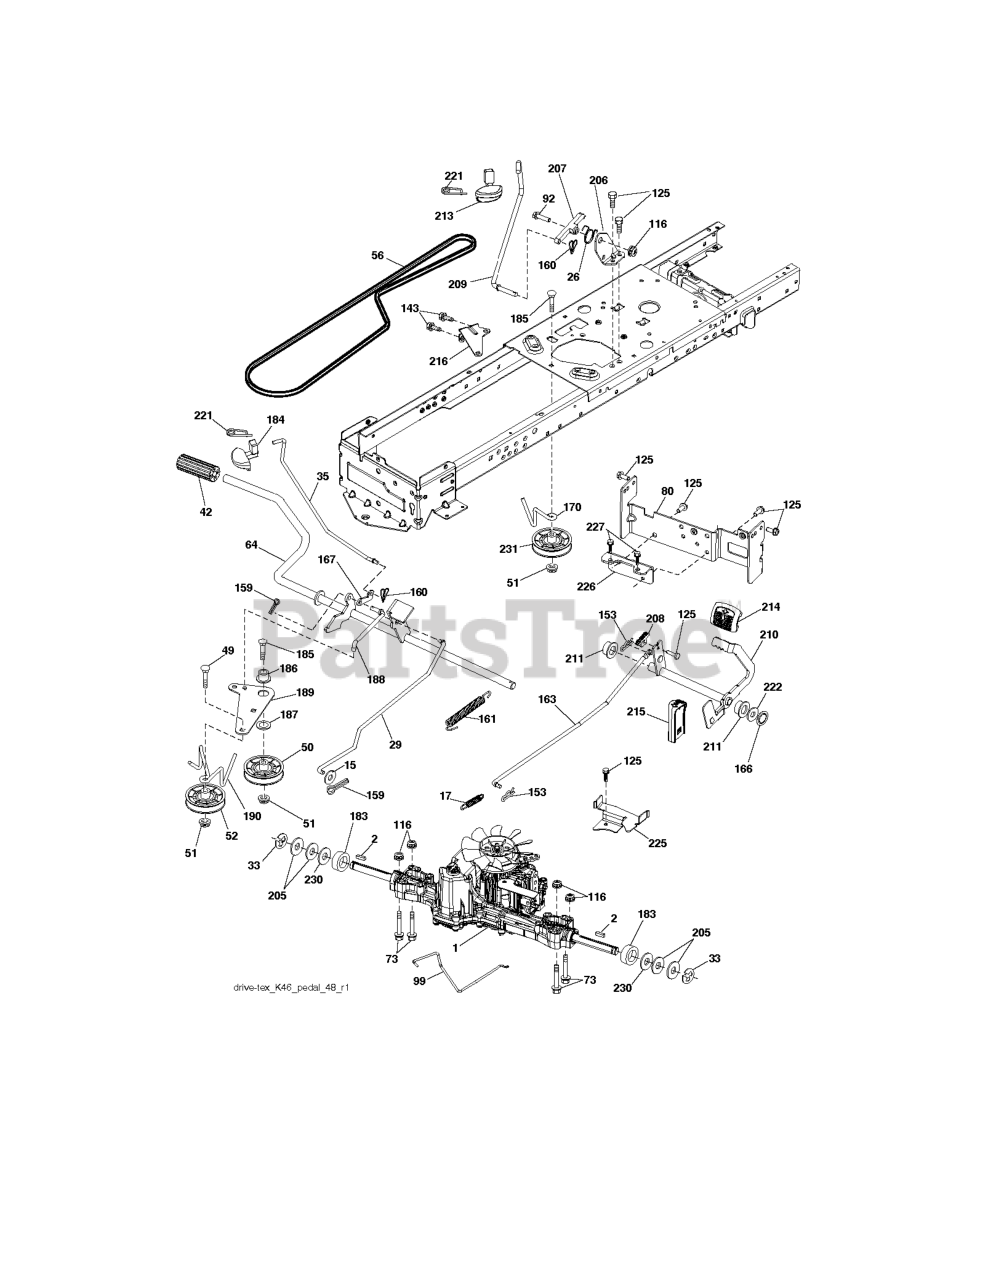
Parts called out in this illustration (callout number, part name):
1	TRANSAXLE(K46BT).PDL.
2	SQUARE KEY
15	WASHER
17	SPRING.BRAKE.K46.GREEN
26	SPRING.RETURN.CRUISE
29	ROD.BRAKE.K46
35	ROD.BRAKE.PARKING.GT.H
42	PEDAL COVER T
50	IDLER.FLAT.910.OFFSET
51	NUT LOCK FLG 3/8-16 UNC
52	IDLER.V-GROOVE.910.OFFSET
56	V-BELT.MOWER.92.40.42/K46
64	SHAFT.ASM.PEDAL.BRK.CNTR
80	STRAP TORQUE
92	BOLT
99	ROD.SPRING.BYPASS.K46.LT.Z
116	NUT LOCK HEX FLANGE 5/16-18
125	SCREW
143	Screw 5/16-18 x 1/2 Hex, Self Tapping 5/16-18 x 1/2
153	RETAINER M
159	COTTER PIN
160	RETAINER CLIP
161	SPRING, RETURN LT
163	ROD.CONTROL.PEDAL.K46
166	NUT.PUSH.625
167	LATCH.BRAKE.SPRING
170	KEEPER.CENTER SPAN.1.688
183	SPACER AXLE
184	HANDLE.PARKG.BRK.HUSQ X667
186	SPACER.RETAINER
187	WASHER 12/32X2X10GA
188	RP.LINK.CLUTCH.GROUND.DRIVE
189	BELLCRANK.GROUND.DRIVE.TEX.
190	KEEPER.BELLCRANK.DRIVE
206	BRKT.MOUNT.LATCH.CRUIS
207	LATCH.CONTROL.CRUISE
208	GEAR.SECTOR.CONTROL.CR
209	ROD.CONTROL.CRUISE.GT.
210	ROCKER.ASM.PEDAL.CONTR
211	BEARING.NYLON
213	KNOB.CONTROL.CRUSIE.HU
214	PEDAL.FORWARD.PAD.TEX
215	PEDAL.REVERSE.TEX.GT.4
216	BRACKET.PULLEY.IDLER.W/TEX
221	RETAINER.SPRING.CLIP.H
222	WASHER 21/32 X 1-1/4 X 10 GA.
225	KEEPER.BELT.TRANSAXLE.K46
226	BRACKET.MOUNT.TORQUE.K46.TLT
227	SCREW.THDROL.5/16-18X3/4.TTY
230	WASHER.HARDENED
231	IDLER.V-GROOVE.1.688.OFFSET
